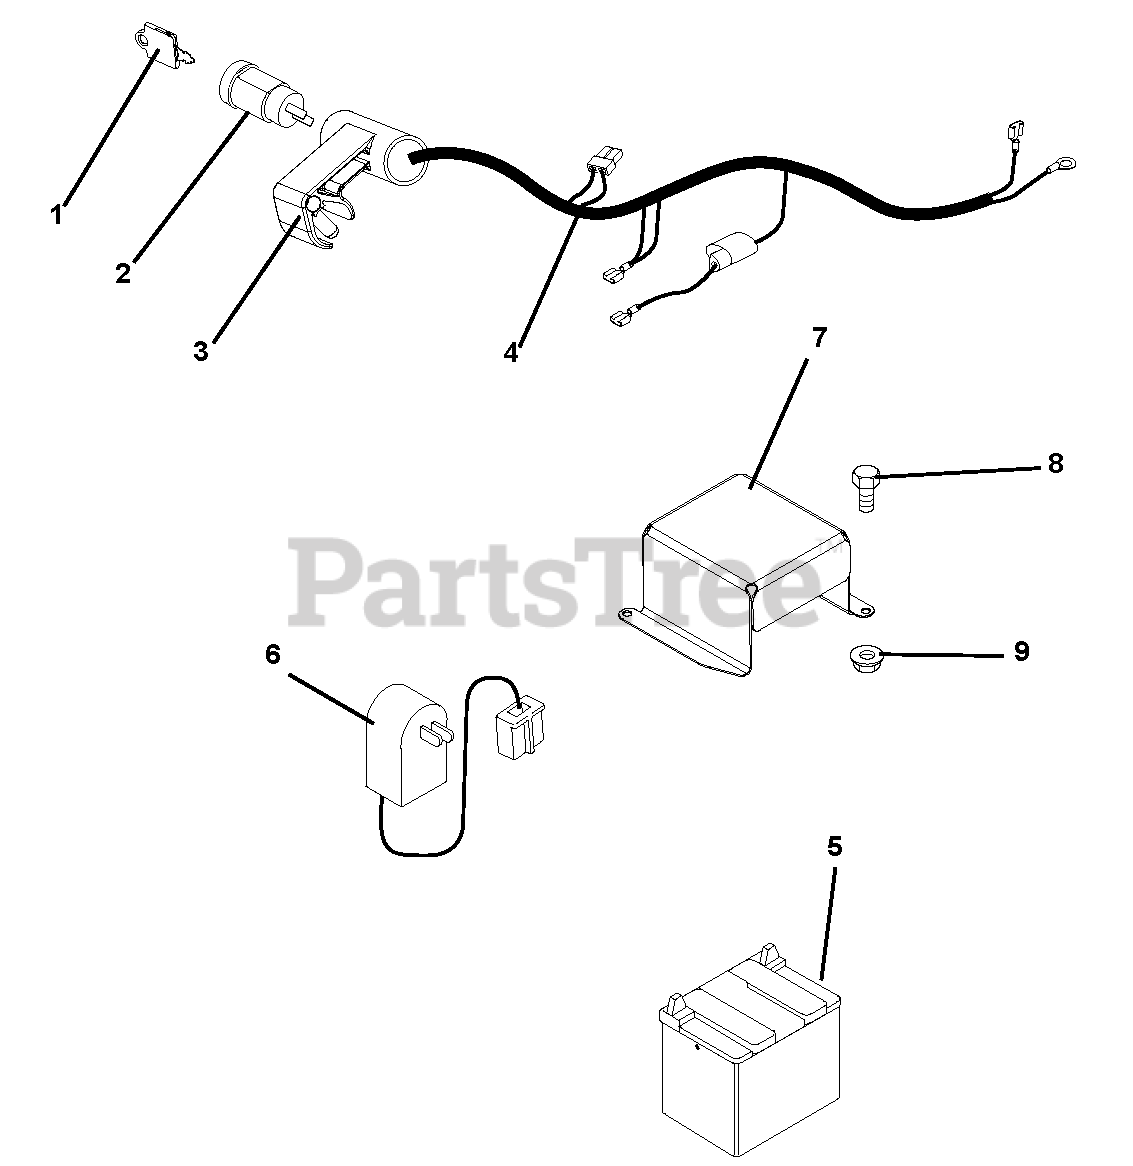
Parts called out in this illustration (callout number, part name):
2	Key, Switch
3	Housing, Switch
4	Harness, Wire
6	Battery, Charger
7	Cover, Battery
8	Bolt, Hex 8-32 x .5
9	Nut, Locking-Nylon 8-32
